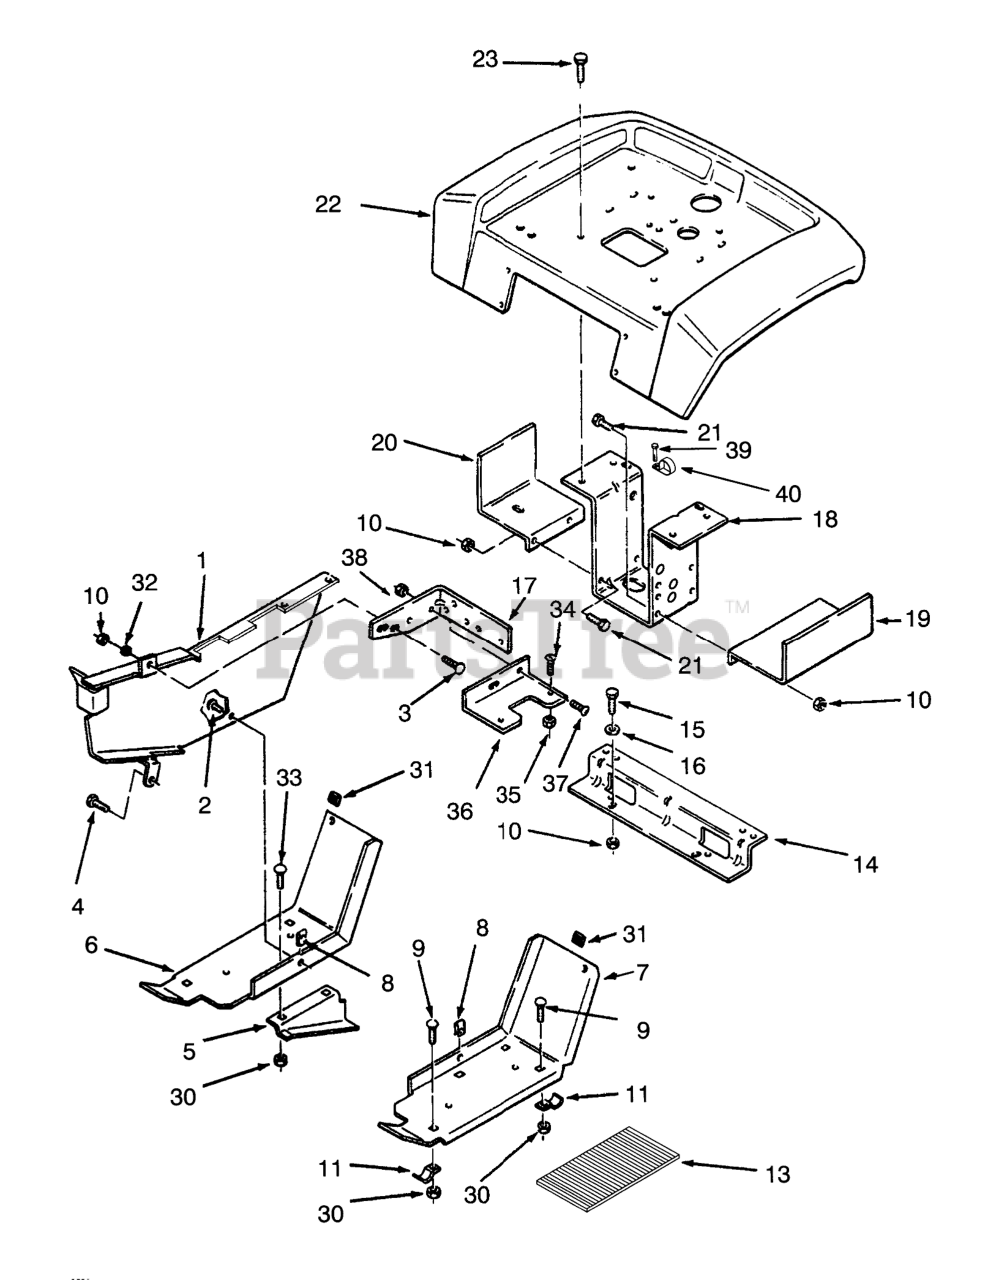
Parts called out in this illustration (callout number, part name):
1	Belt Guard
2	SCREW-PPH
3	BOLT-CARR
4	Bolt
5	GUID-LOWER BLTR
6	Footrest-RH
7	FOOTREST LH R
9	BOLT-CARR
10	NUT-LOCK, NI
11	BRACKET
13	PAD FOOTREST
14	BRACKET-FENDER B
15	SCREW-HH
16	WASHER-PLAIN
17	BRACKET-BELTB
18	Bracket-Fender
19	Fuel Tank Support LH
20	Support-FueITank RH
21	SCREW-HH
22	Fender
23	Bolt
30	NUT-LOCK, NI
31	BUMPER SJ5514 BLACK
32	NUT-PUSH
33	BOLT-CARR 5/16 SN
34	SCREW-PAN
35	Nut
36	BRKT-FUS HLDERB
37	SCREW-HH
38	NUT-LOCK, NI
39	SCREW-HH, LOCK
40	CLIP
